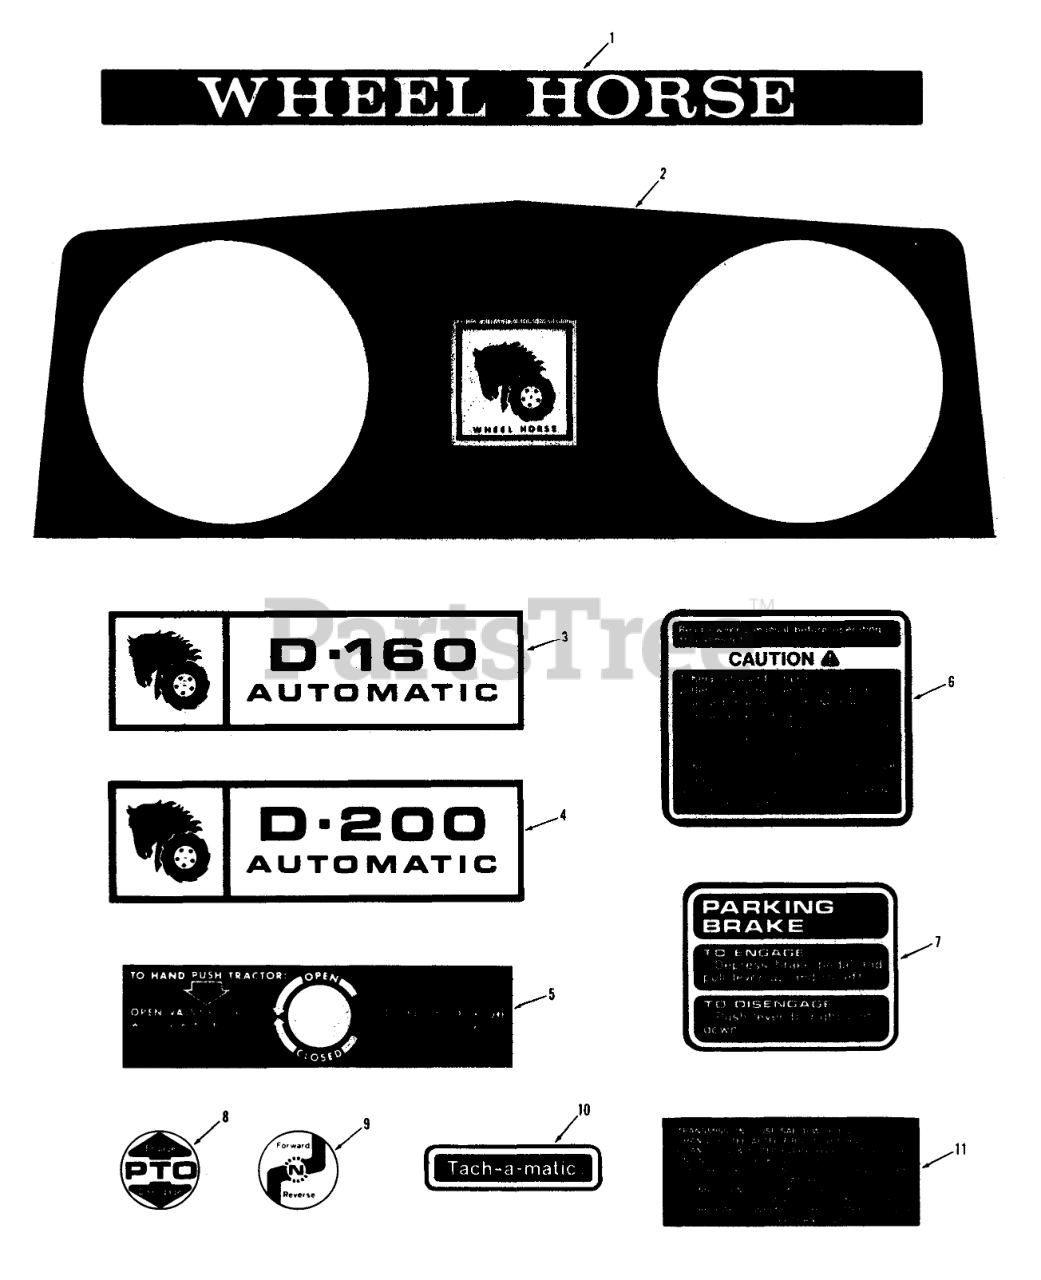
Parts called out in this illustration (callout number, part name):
1	Decal
2	Decal
4	Decal-"D-200 Automatic"
5	Decal
6	Decal-Caution
7	Decal-Parking Brake
8	Decal-Clutch Knob
9	Sleeve
10	Decal-Tach-a-matic
11	Decal-Maintenance
